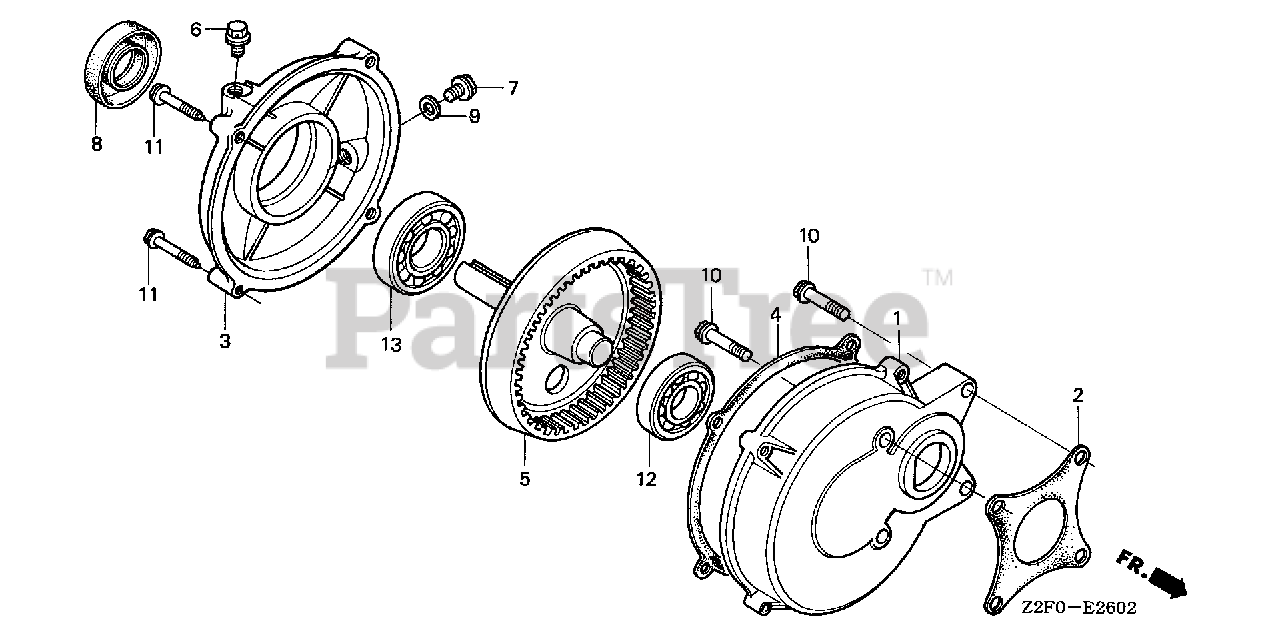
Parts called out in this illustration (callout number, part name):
1	CASE, REDUCTION
2	GASKET, REDUCTION CASE
3	COVER, REDUCTION
4	GASKET, REDUCTION COVER
5	SHAFT, P.T.O. (86T)
6	BOLT, BREATHING
7	BOLT, DRAIN PLUG (12X15)
8	OIL SEAL (25X41X6) (NOK)
9	WASHER, DRAIN PLUG (12MM)
10	BOLT, FLANGE (8X32)
11	BOLT, FLANGE (8X35)
12	BEARING, RADIAL BALL (6204)
13	BEARING, RADIAL BALL (6305)
